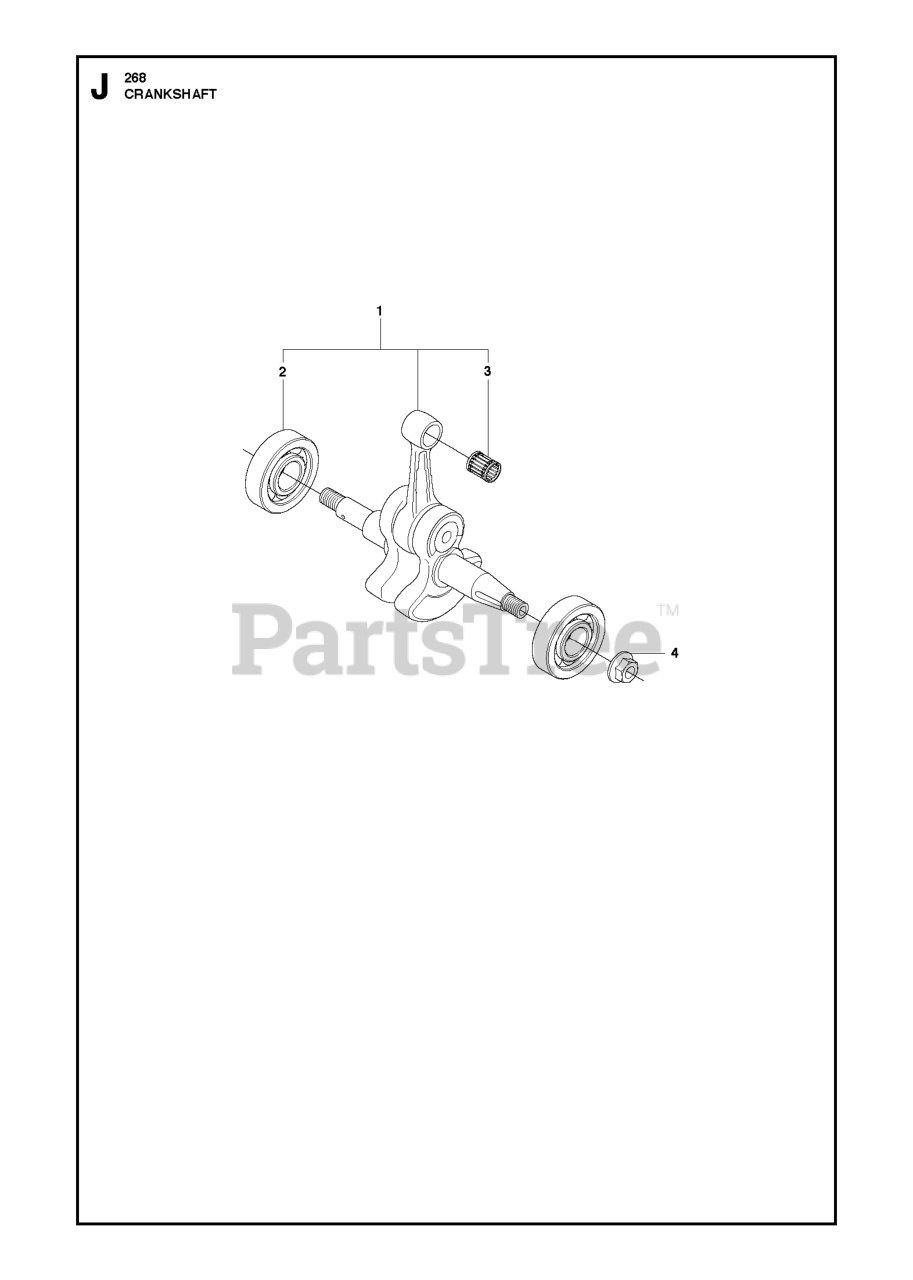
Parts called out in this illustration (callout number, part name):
1	CRANKSHAFT
2	BALL BEARING
3	NEEDLE BEARING PISTON PIN 12X1
4	NUT W/ WASHER
